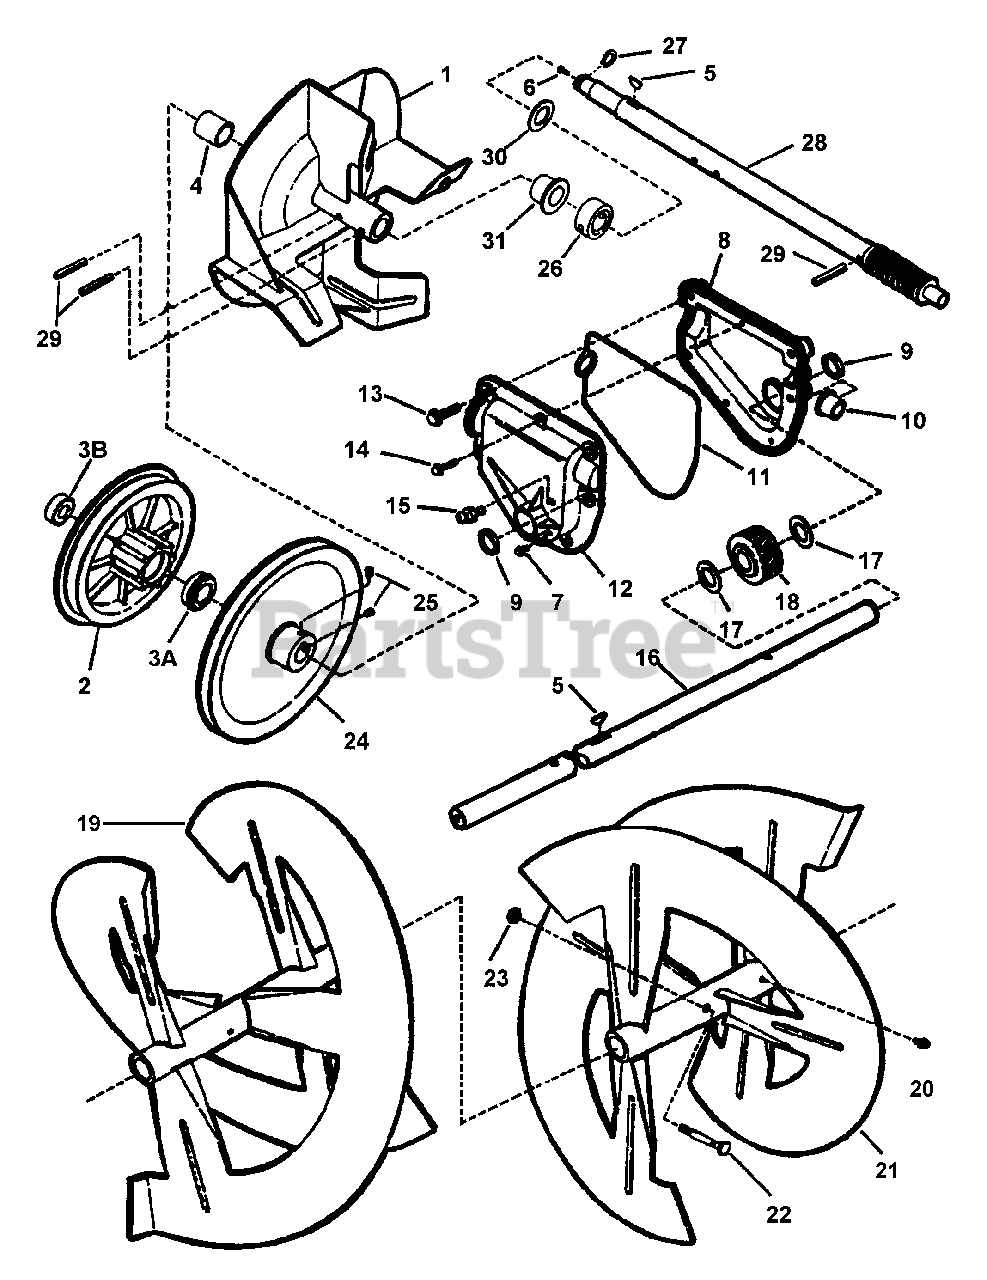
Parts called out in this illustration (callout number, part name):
1	WELDMENT, Impeller (Fan)
2	ASSEMBLY, Drive Plate
3A	BEARING, Ball
3B	BEARING, Ball
4	SPACER, .76 I.D. x 1" O.D. x .25" Thick
5	KEY, #9 (3/16 x 3/4") Woodruff
6	SCREW, 1/4-20 x 1/2" Truss Head Self-Tapping (Torx)
7	SCREW, #10-24 x 1/2" Hex Washer Self-Tap (Torx)
8	COVER, Gear Case (Left Hand)
10	BUSHING
11	"O" RING
12	COVER, Gear Case (Right Hand)
13	SCREW, 1/4-20 x 3/4" Hex Washer Self-Tapping
14	SCREW, #10-24 x 5/8" Hex Washer Self-Tap, Grade 5
15	FITTING, Lube 1/4-28 Thread Forming
16	SHAFT, Auger
17	WASHER, Thrust
18	GEAR, Worm
19	AUGER, (Left Hand)
20	LUBE FITTING, Straight (press-fit for .187 dia. Hole)
21	AUGER, (Right Hand)
22	PIN, Shear, .248 ID. X 1.75 LG
23	COTTER PIN, .094 X0.750 BLK
24	PULLEY, 8.36" O.D.
25	SCREW, 5/16-18 x 5/16 Hex Socket Set
26	COLLAR
27	RING, 1/2" Heavy Duty External Retaining
28	SHAFT, Pinned Impeller (Worm)
29	ROLL-PIN, 1/4 x 1-1/4"
30	WASHER, Thrust
31	BEARING
